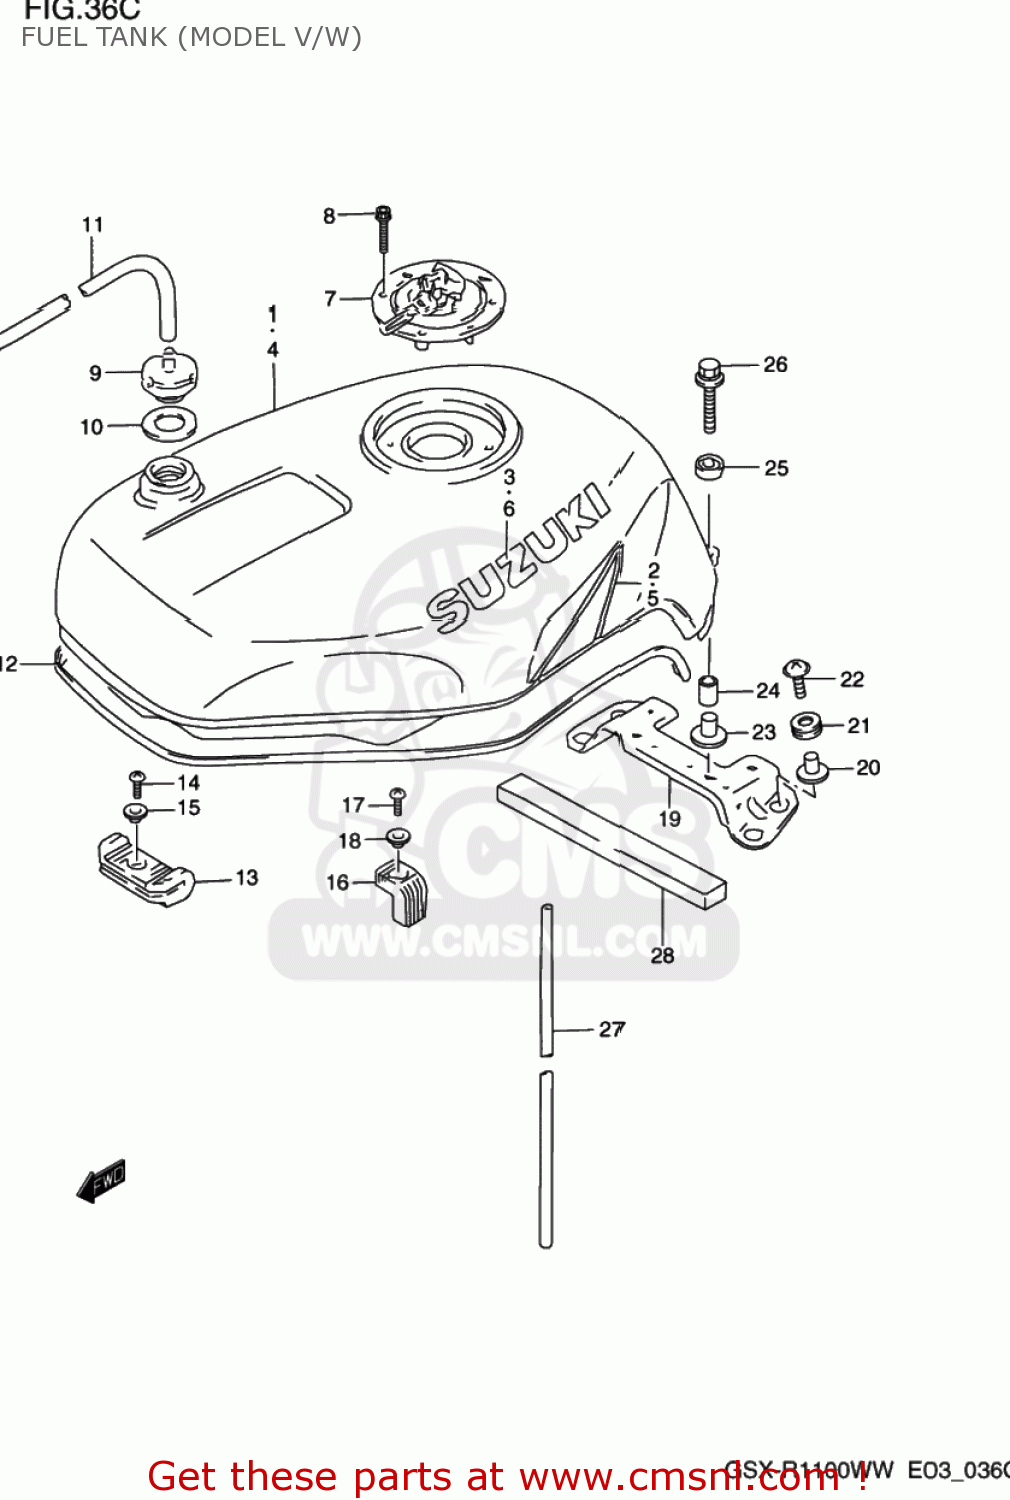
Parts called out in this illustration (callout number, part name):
1	TANK ASSEMBLY,FUEL
2	TAPE SET,FUEL TANK
3	EMBLEM,FUEL TANK
4	TANK ASSEMBLY,FUEL
5	TAPE SET,FUEL TANK
6	EMBLEM,FUEL TANK
7	CAP SET,FUEL TANK
8	BOLT(5X20)
9	PLUG,FUEL TANK BREATHER
10	GASKET 27X40X2.5 (NAS)
11	HOSE(5X8.2X600)
12	MOLDING
13	CUSHION,FUEL TANK FR
14	SCREW
15	WASHER
16	CUSHION,TANK SIDE
17	SCREW
18	WASHER
19	BRACKET,FUEL TANK RR
20	WASHER
21	CUSHION
22	SCREW(6X25)
23	CUSHION
24	SPACER(6.5X9X18)
25	CUSHION
26	BOLT
27	HOSE(7X10.2X2000)
28	CUSHION,AIR SEAL
